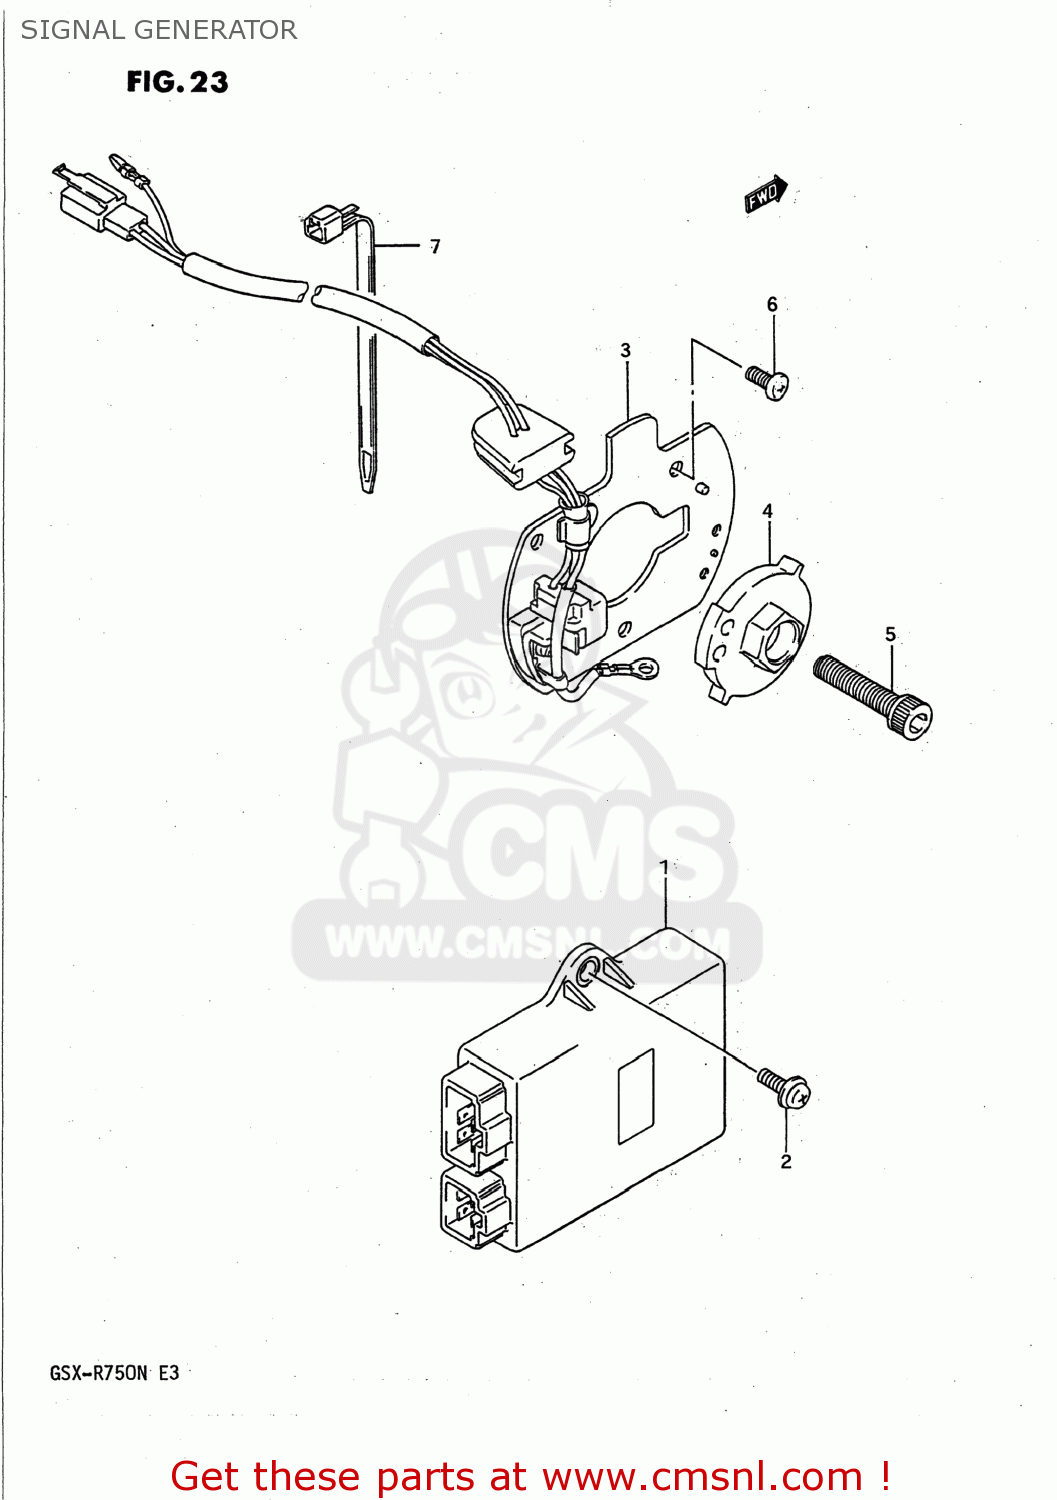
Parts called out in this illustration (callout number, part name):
1	IGNITOR
2	SCREW
3	GENERATOR ASSY,SIGNAL
4	ROTOR,SIGNAL
5	BOLT
6	SCREW
7	CLAMP(L:125)
